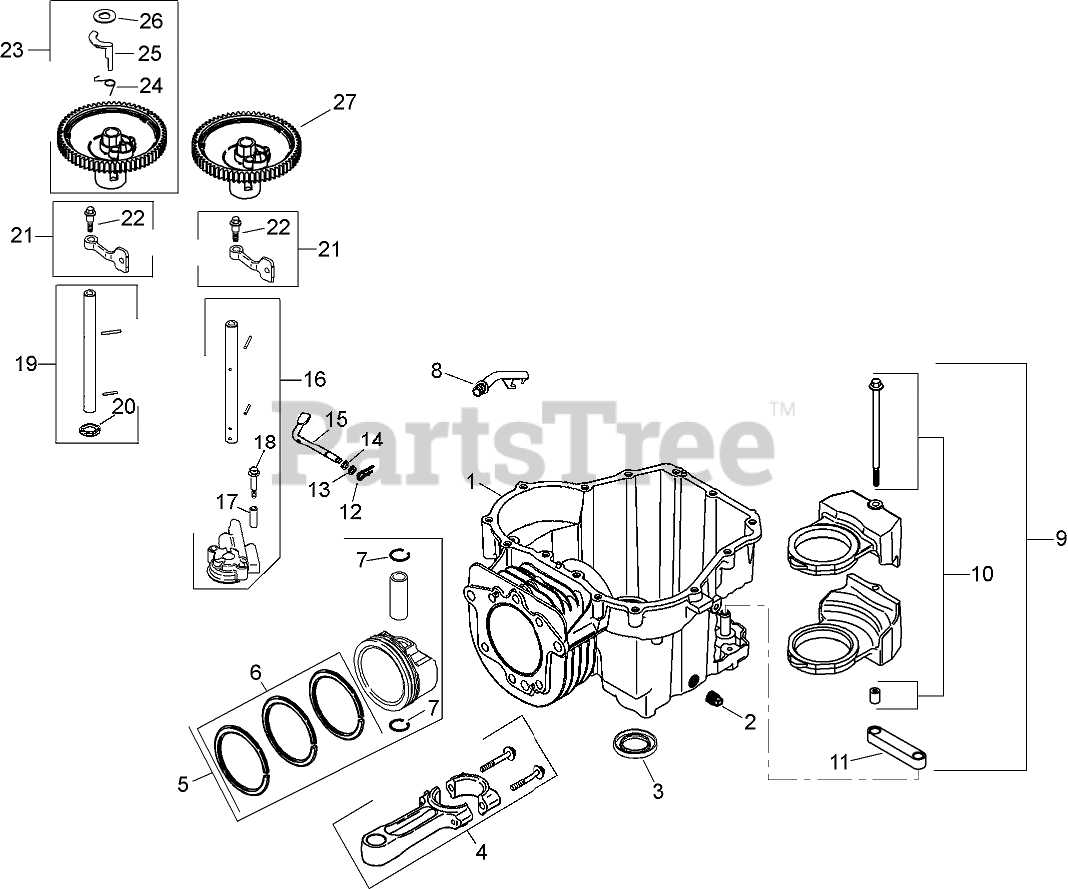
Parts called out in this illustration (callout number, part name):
2	PLUG-PIPE, SQ HD (3/8)
3	Seal-Oil
4	Connecting Rod ASM
5	PISTON W/RING SET (94MM) (INCLUDES 6,7)
6	Ring Set (94 mm)
7	Retainer-Pin, Piston
8	Tube-Back, Drain
9	BALANCE WEIGHT KIT (INCLUDES 10,11)
10	LOCATING PIN ASM
11	LINKAGE-WEIGHT, BALANCE
12	Clip-Pin, Hitch
13	WASHER-FLAT (6mm)
14	WASHER-FLAT (1/4)
15	Shaft-Cross, Governor
16	OIL PUMP ASM (INCLUDES 17, 18)
17	Spacer-Screw, Oil Pump
18	Screw-Pump, Oil
19	Exhaust Camshaft Center ASM (INCLUDES 20)
20	WASHER-THRUST
21	CAM LEVER ASSEMBLY (INCLUDES 22)
22	Bolt-Shoulder (M6x1x26)
23	CAM GEAR ASM (EXHAUST) (INCLUDES 24-26)
24	Spring-A C R
25	Weight-A C R
26	Washer-Thrust, A C R
27	CAM GEAR ASM (INTAKE)
